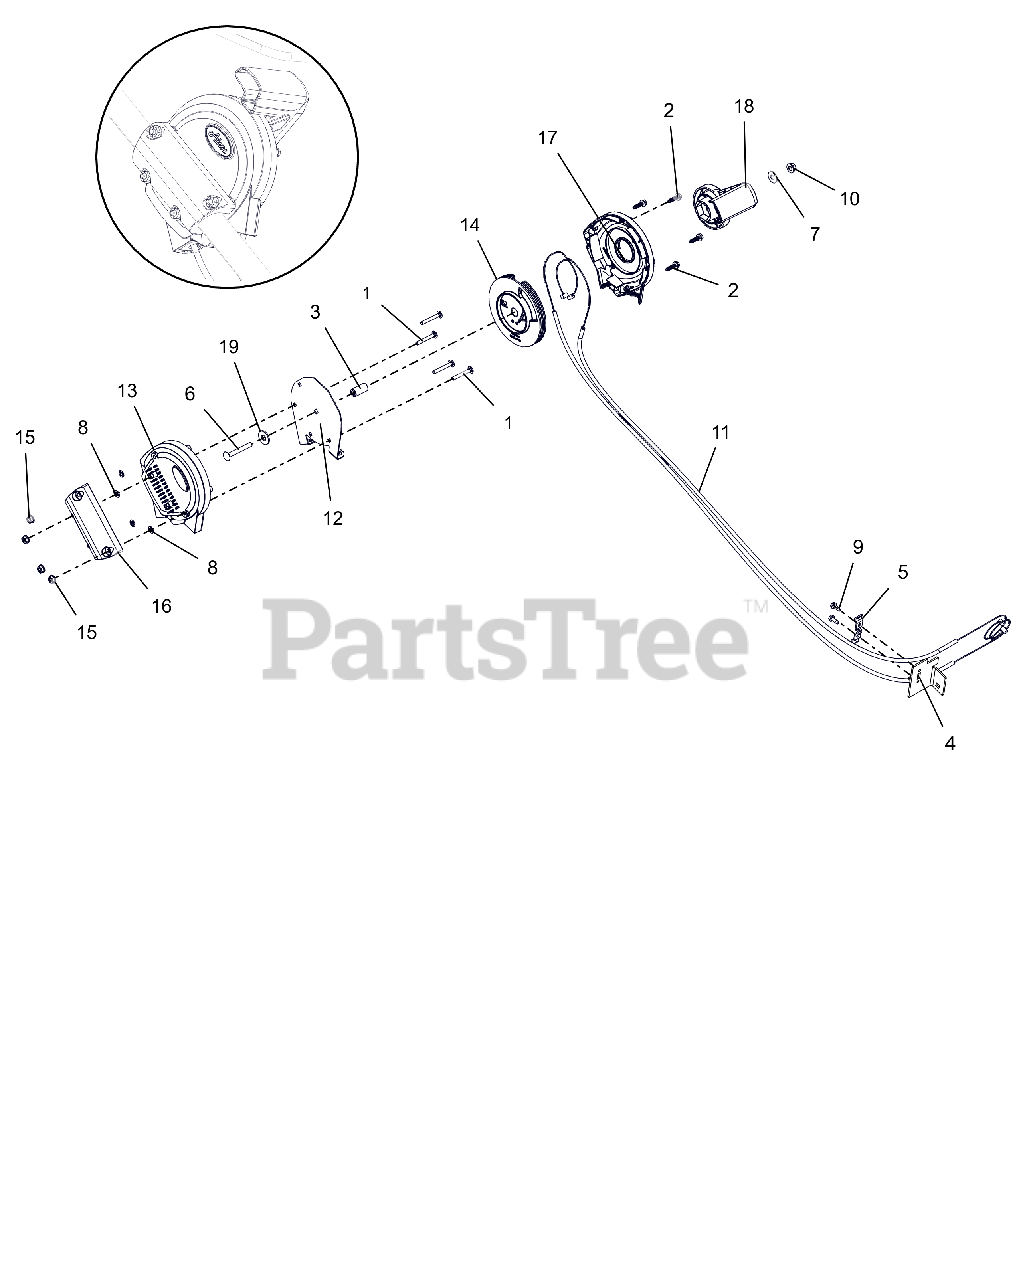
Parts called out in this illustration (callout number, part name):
1	@BLT-RDHDSQNK 10-24X1.50 G2 YZ
2	SCR-TAP #12X.75 BOSS INDHXHD
3	BSHG, SLV .265X.505X.995
4	BRKT, CABLE ANCHOR
6	@BLT-RDHDSQNK .25-20X2.00 G5YZ
7	@WSHR-FL-STL.312X.734X.065 YWZ
8	NUT-PUSH-BOLT-RET #10
9	@SCR-TAP 10-24X.50 HWH TR YWZC
10	@NUT-LK-TOP-FLG .25-20 YWZC
11	CABLE, CHUTE
12	FRAME, REMOTE CHUTE CONTROL
13	REMOTE HOUSING, RH
14	PULLEY, 4.25" POLY
15	@NUT-LK-TOP-FLG 10-24 YWZC
16	REMOTE, BRKT
17	REMOTE HOUSING, LH
18	REMOTE HANDLE
19	@WSHR-FL-STL.38X.875X.083 YWZC
